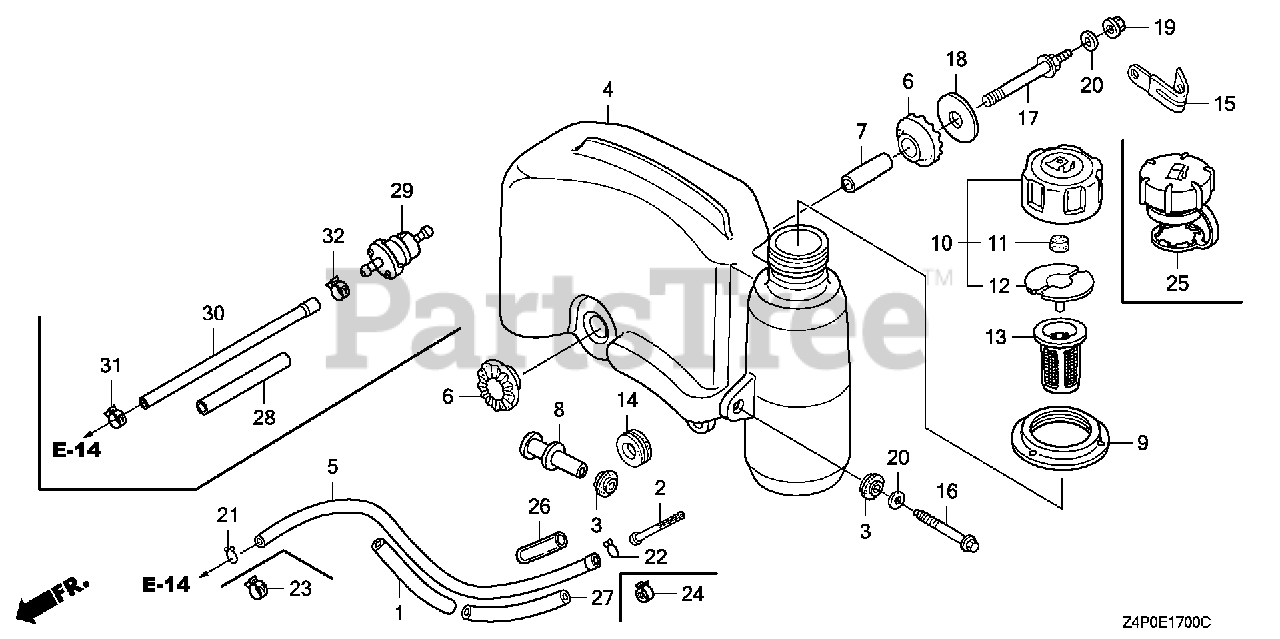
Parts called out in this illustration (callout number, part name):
20	WASHER, PLAIN (6MM)
28	RUBBER, SUPPORTER (107MM)
29	STRAINER, FUEL
29	FILTER, FUEL
30	TUBE, FUEL (FKM)
30	TUBE, FUEL (4.2X210) (FKM)
31	CLIP, TUBE (D8)
32	CLIP, TUBE (D8)
32	CLIP, TUBE (D8.5)
